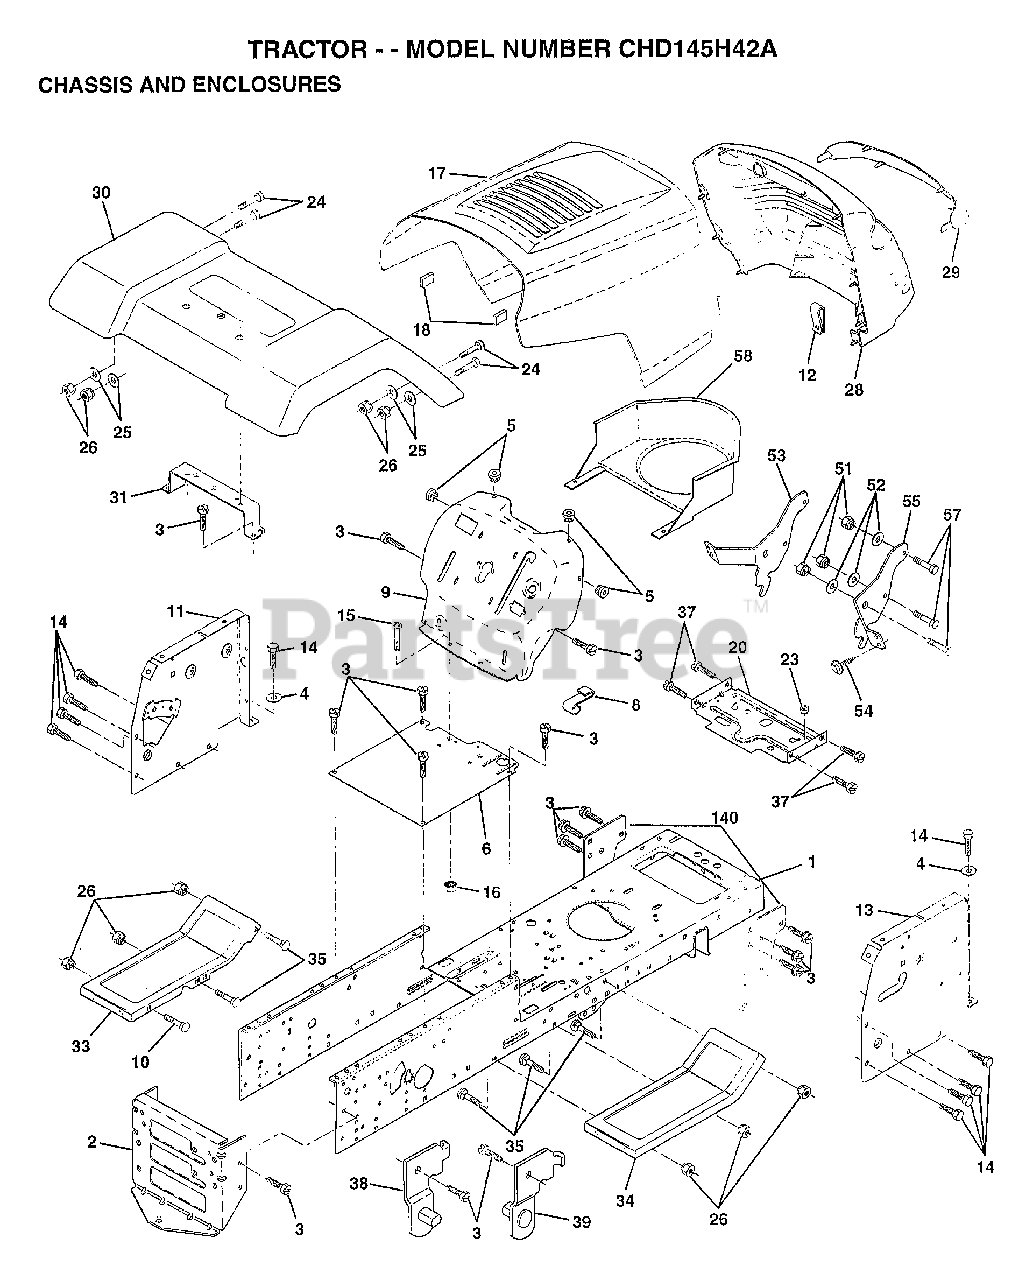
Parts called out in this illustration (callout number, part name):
1	CHASSIS ASM
3	SCREW
4	WASHER
5	BUMPER-HOOD/DASH
6	SADDLE
8	CLIP.RETAINER
9	DASH.SILKSCREENED
11	"PANEL-DASH,LH"
12	CLIP.TINNERMAN
14	SCREW LT
15	SCREW
20	"PLATE-MTG,BATT/FU"
24	BOLT
25	WASHER
26	NUT
28	GRILLE-MS428
29	LENS GRILLE
30	FENDER ASM LT W/S
31	BRKT FENDER
33	FOOTREST LH
34	FOOTREST RH
35	BOLT
37	SCREW LT
38	BRACKET ASM LH
39	BRACKET ASM RH
51	NUT
52	WASHER
53	BRACKET.GRILLE.LH
55	BRACKET.GRILLE.RH
58	AIR DUCT
140	BRKT SUSPENSION
